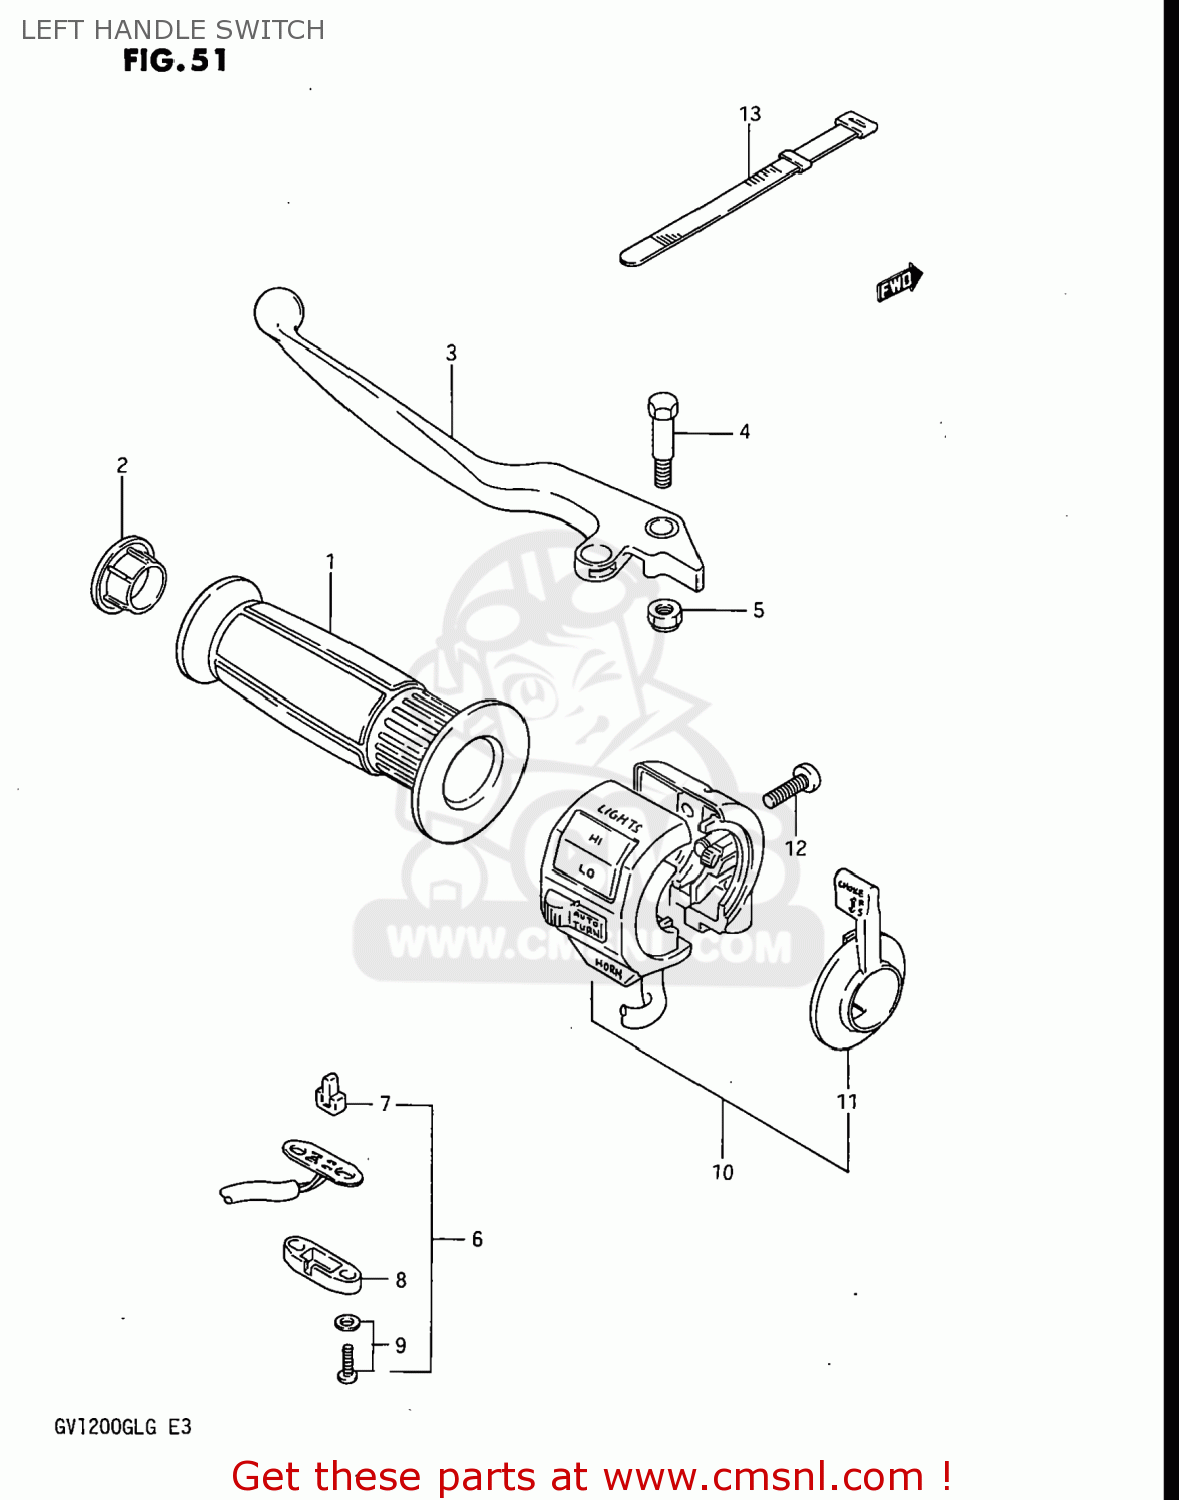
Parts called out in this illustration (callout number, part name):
1	GRIP,LEFT
2	CAP,GRIP END
3	LEVER,CLUTCH (BLACK)
4	BOLT,LEVER
5	NUT
6	SWITCH ASSEMBLY,CLUTCH
7	CONTACT,SWITCH
8	COVER,FR BK TERMINAL BASE
9	SCREW
10	SWITCH ASSEMBLY,HANDLE,LEFT
11	LEVER,CHOKE
12	SCREW 5X20
13	CLAMP(L:120)
